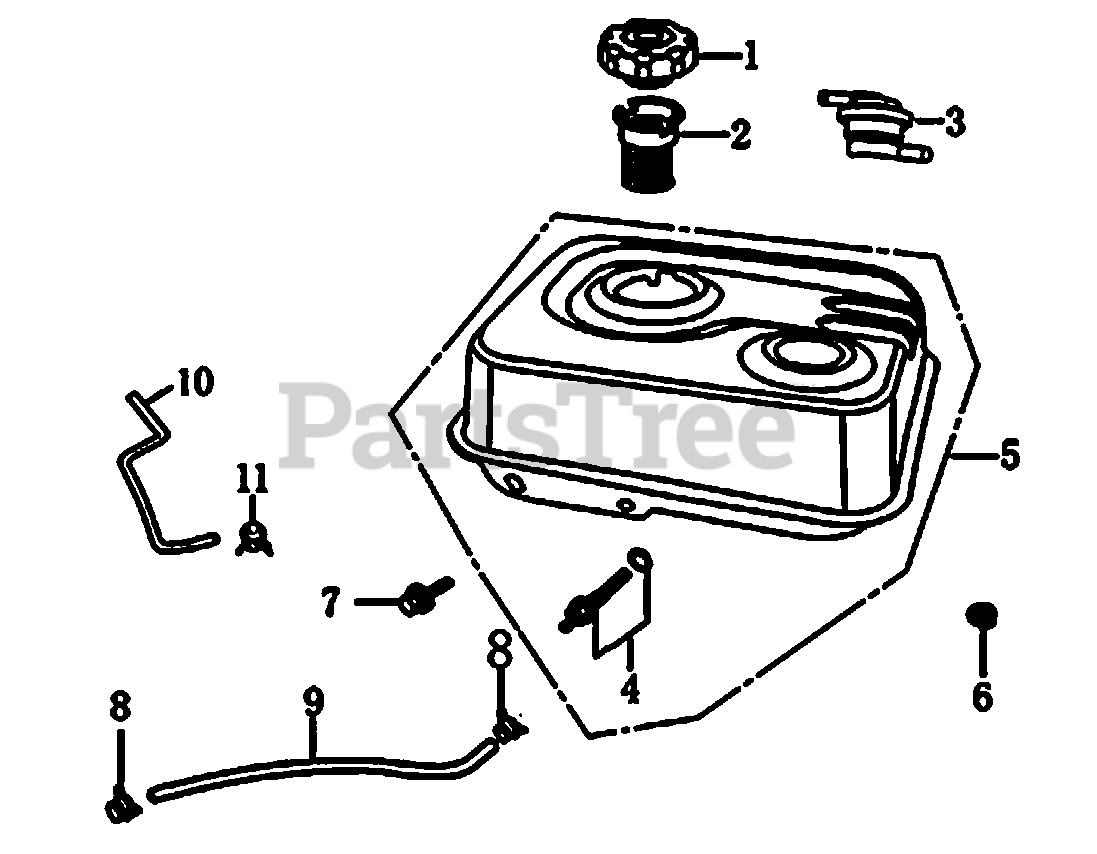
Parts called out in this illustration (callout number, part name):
1	CAP COMP ., FUEL FILLER
2	FILTER , FUEL
3	VALVE, ROLL OVER
4	JOINT ASSY., FUEL TANK
5	TANK, FUEL W/JOINT ASSY.
6	NUT, FLANGE
7	BOLT, FLANGE, 8X25
9	HOSE, FUEL
10	HOSE, ROV TO A/C
